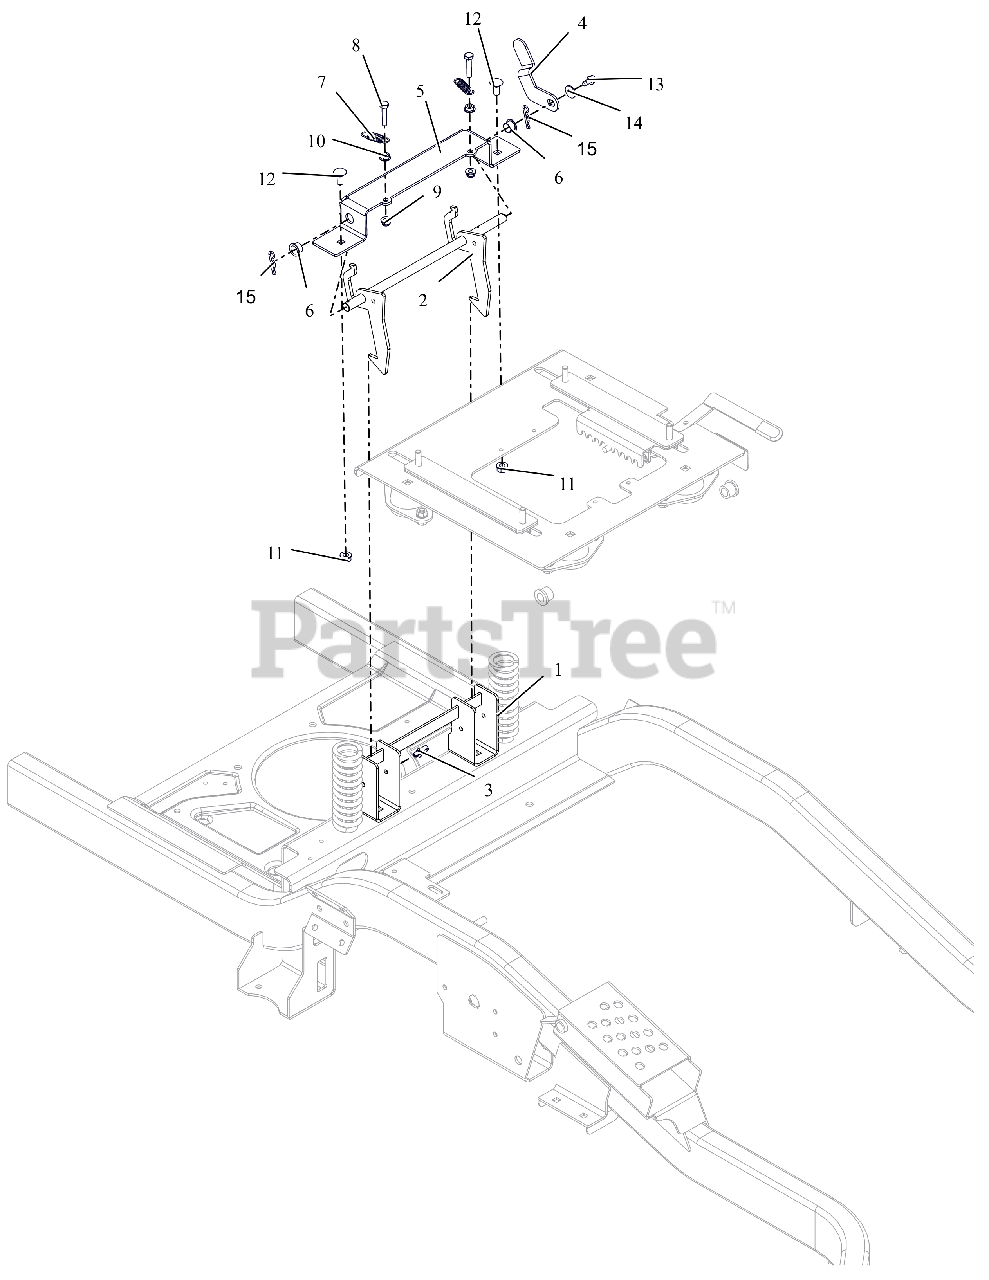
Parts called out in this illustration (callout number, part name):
1	WLDMT, LATCH RECEIVER
2	WLDMT, SEAT LATCH
3	ROUTING CLIP (1/2" ID)
4	LEVER, SEAT LATCH RELEASE
5	BRKT, SEAT HOOK MTG.
6	BUSHING, POLYLINER-.50 SPLIT
7	SG-TENS .063X.44X1.56
8	BLT, HEX .25-20X1.25 G5 ZCC
9	NUT,NYL-FLG .25-20 GF ZCC
10	NUT-SPNLK-FLG .25-20 ZC120
11	NUT,LK-CTR-FLG .31-18 GF ZCC
12	BLT,RHSN .31-18X.75 G5 ZCC
13	SCR-TAP .25-20X.50 HWH ZCC
14	WSHR, FLT .312X.734X.065 ZCC
15	PIN, HAIR .08X.38X1.42 ZCC
